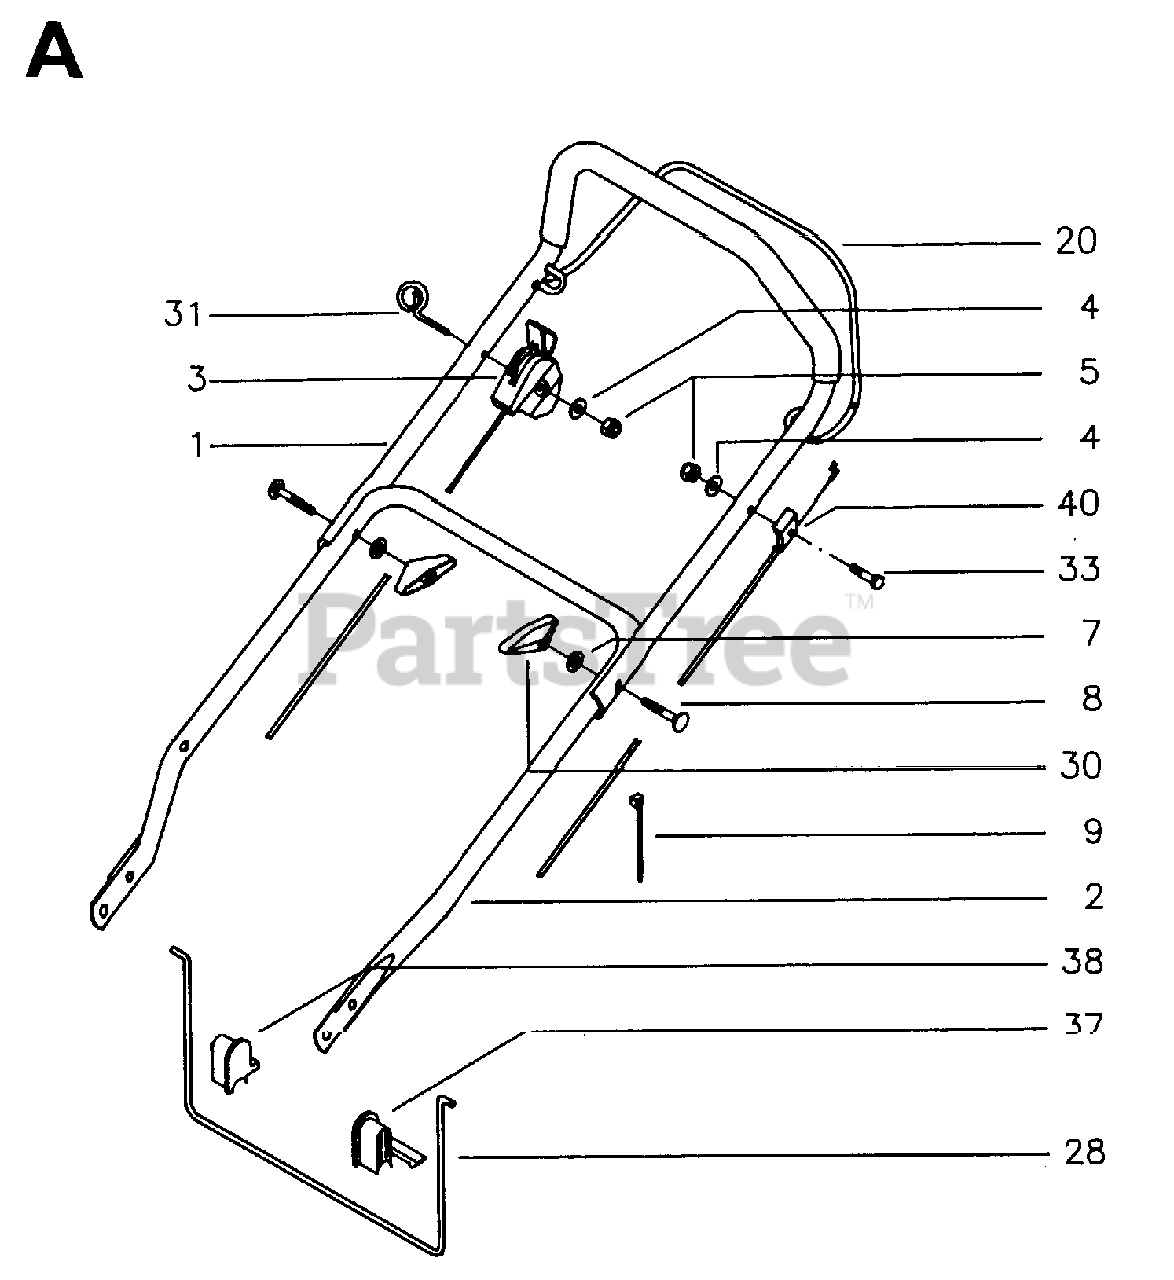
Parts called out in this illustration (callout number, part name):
5	LOCKNUT M6
28	HANDLE BAR
33	BOLT FLANGE
